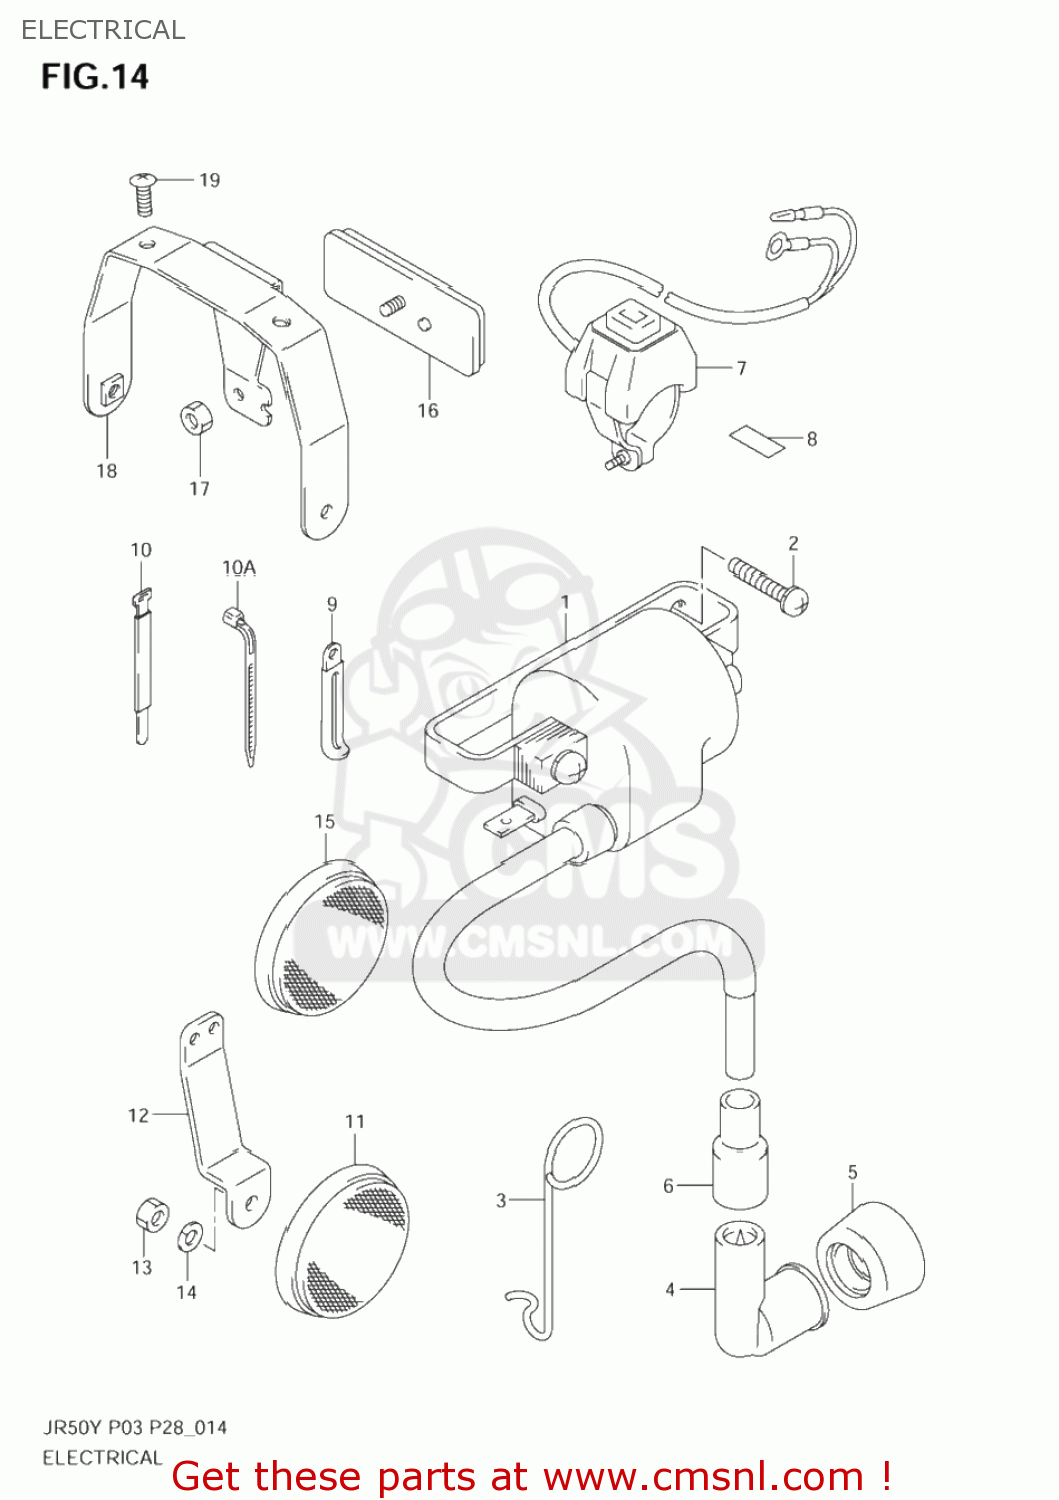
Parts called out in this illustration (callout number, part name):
1	UNIT & COIL ASSY,IGNITION
2	SCREW
3	CLIP
4	CAP ASSY,SPARK PLUG
5	SEAL,SPARK PLUG
6	SEAL,HIGH TENSION CORD
7	SWITCH ASSY,ENGINE STOP
8	LABEL,ENGINE STEP SWITCH
9	CLAMP(L:45)
10	CLAMP
10A	CLAMP(L:165)
11	REFLEX REFLECTOR,FR
12	BRACKET,FR SIDE RR
13	NUT
14	LOCK,WASHER
15	REFLEX REFLECTOR,RR
16	REFLECTOR ASSEMBLY,REAR
17	NUT
18	BRACKET,SIDE & RR
19	SCREW 6X12
